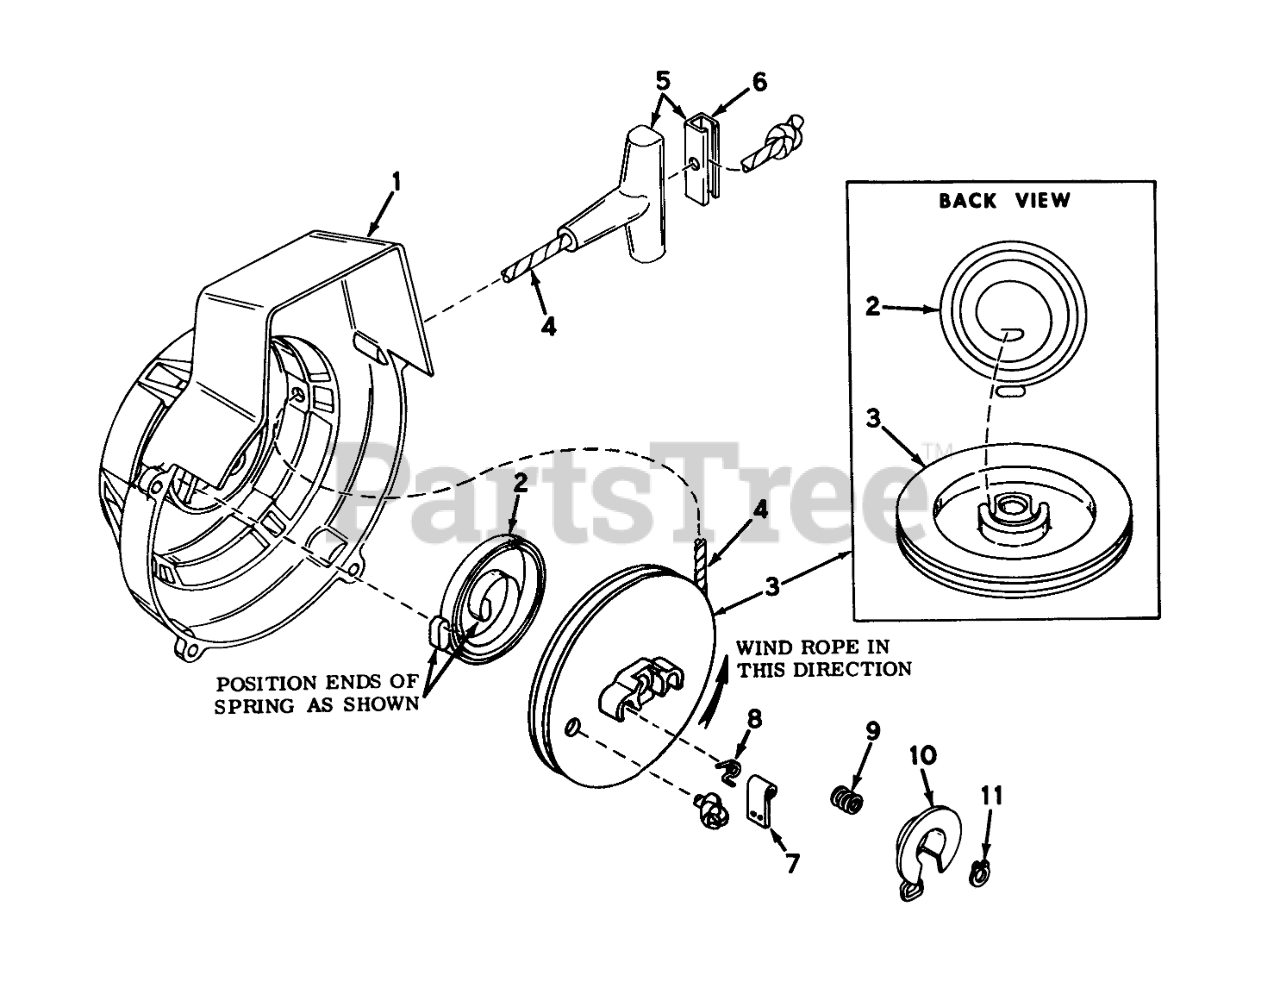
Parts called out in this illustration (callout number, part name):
1	Housing Assy., Shroud & Starter
2	Spring, Rewind
3	Pulley, Starter Rope (Incl. No. 8)
4	Rope-Starter
5	Handle Assembly, Starter Rope (Incl. No. 6)
6	Insert, Handle
7	Dog, Starter
8	Retum Spring, Left Hand Wound
9	Spring, Brake
11	"E" Ring Truarc
